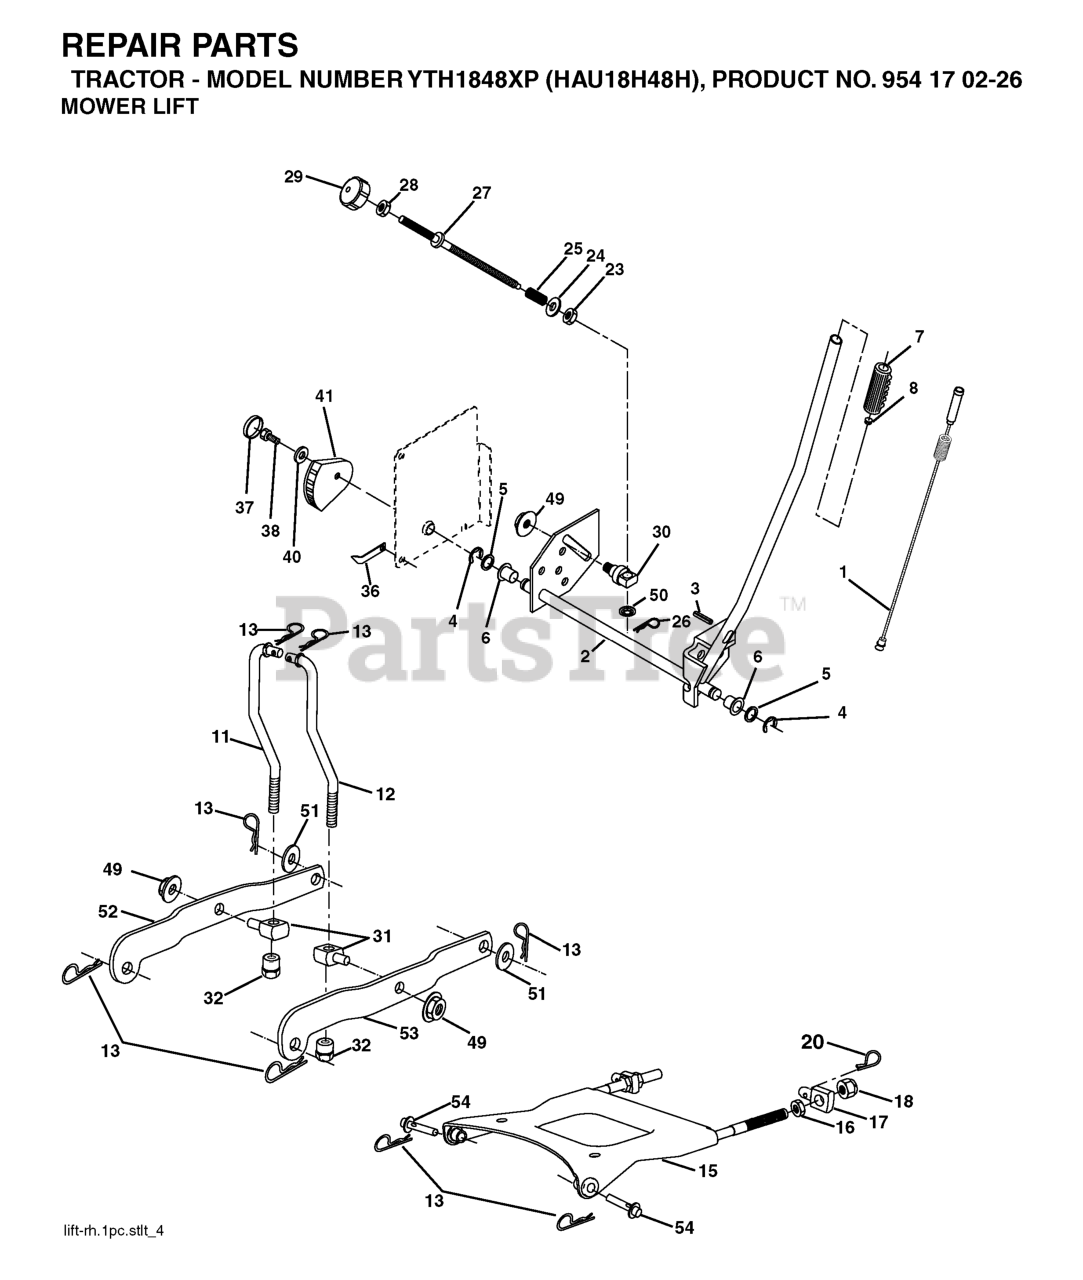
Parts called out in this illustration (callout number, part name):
1	WIRE.ASM.INNER.SP
2	SHAFT.ASM.LIFT.RH.INF
3	PIN GROOVE
4	RETAINING RING LT
6	BEARING.NYLON
7	GRIP HANDLE
8	PLUNGER BUT KIT
11	LIFT LINK LH
12	LIFT LINK RH
13	RETAINER-SPRNG RB
15	PLATE ASM SUSP FRONT
16	NUT.HEX.JAM.1/2-13
18	NUT.LK.W/WSH.1/2.
20	SPRING RETAINER
26	RETAINER CLIP
27	ROD ADJ LIFT
28	NUT
29	KNOB INF 3/8-16
32	NUT, LIFT LINK 7/16-20
36	POINTER, HEIGHT INDICATOR(2 2)
38	SCREW 5/16-18X1
41	IND. HEIGHT STLT
49	NUT
50	NUT PUSH M
51	Washer 1 17/32 X 7/8 X 16 Ga
52	ARM SUSP. REAR LH
53	ARM SUSP REAR RH
54	PIN.FLANGE
